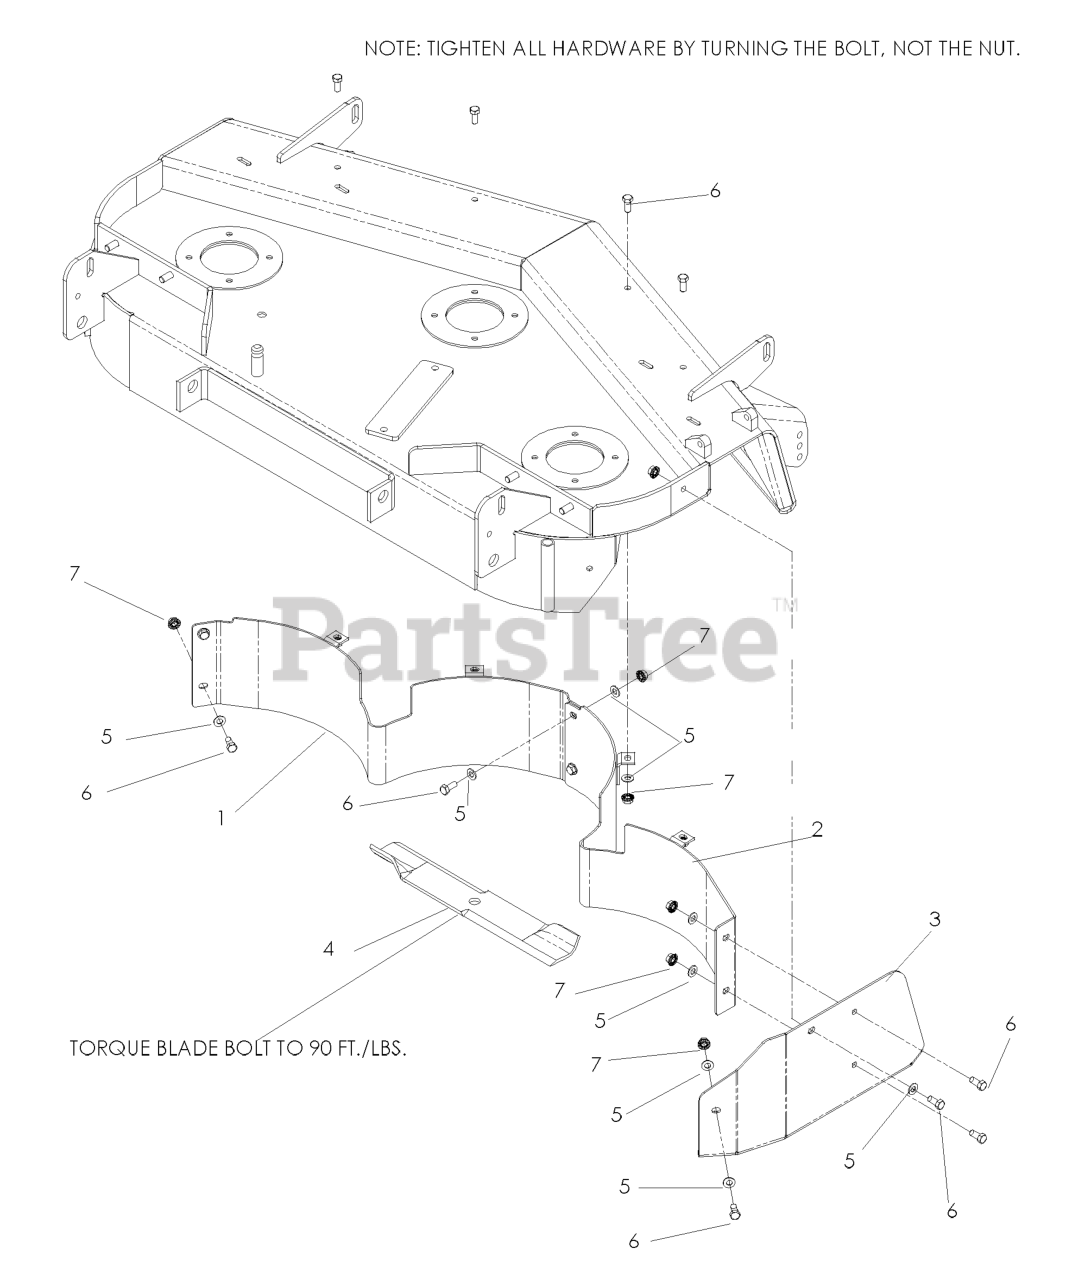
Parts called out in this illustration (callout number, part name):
1	BAFFLE WLDMT, 61" L.H. MULCH
2	BAFFLE WLDMT 61" R.H. MULCH
3	MULCH CAP 61
4	BLADE MULCH 21"
5	FLAT WASHER 5/16 SAE
6	HCS 5/16C X 3/4
7	NUT 5/16C WHIZ
